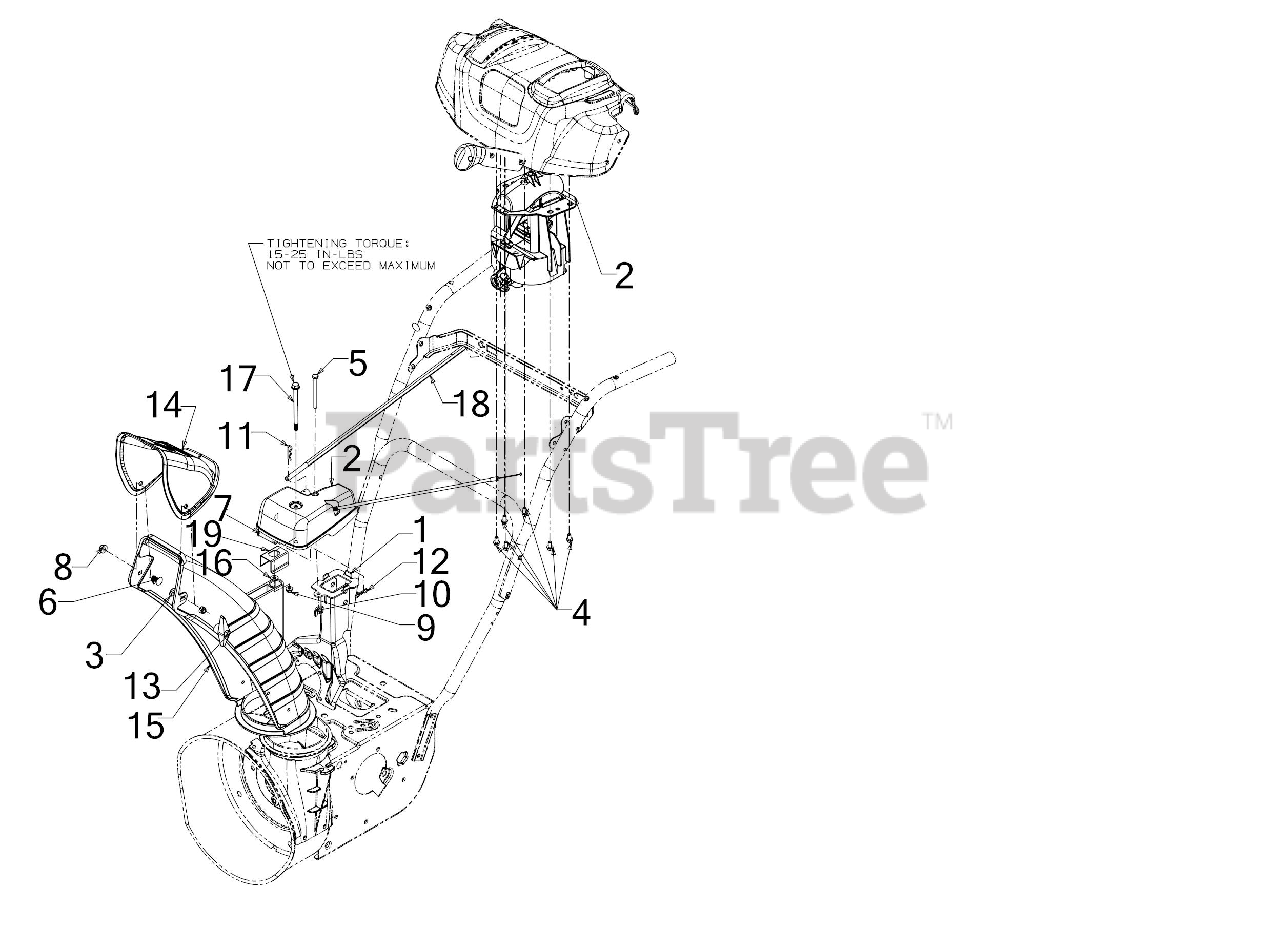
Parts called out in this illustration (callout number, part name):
1	CHUTE SUPPORT BRACKET ASSEMBLY
2	CHUTE CONTROL ASSEMBLY
3	CARRIAGE BOLT 5/16-18 x 1
4	HEX SCREW 1/4-15 x .50
5	SCREW 1/4-20 x 3.0 GR5
6	CARRIAGE BOLT 5/16-18 x .75
7	CLEVIS PIN 3/8 x 1.87
8	FLANGE LOCK NUT 5/16-18
9	FLANGE LOCK NUT
10	WING NUT 1/4-20
11	INTERNAL COTTER PIN
12	BOW TIE COTTER PIN 1/4-5/16
13	WING NUT KNOB
14	UPPER CHUTE
15	LOWER CHUTE 5" DIA
16	FLAT WASHER
17	SHOULDER SCREW
18	CHUTE ROTATION ROD
19	CHUTE BRACKET
